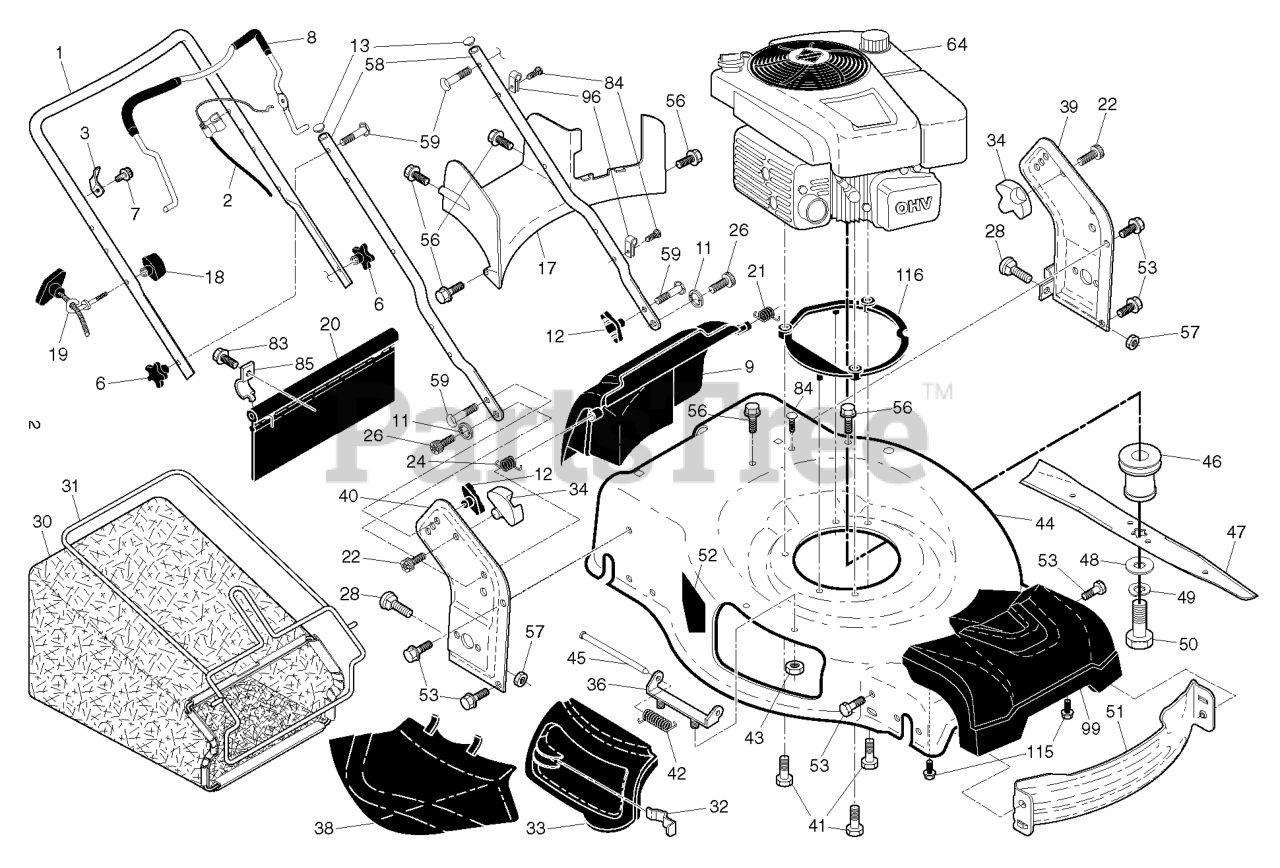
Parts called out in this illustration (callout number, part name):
1	HANDLE.UP.3POS.BS.AW2.GREY
2	CABLE.MZR.50.SNAP-IN
3	BRACKET.UPSTOP.RT
6	KNOB.HANDLE.PLASTIC.STAR.BLACK
8	BAIL.OVER.MOLD.ERGO.MZR.ORANGE
9	DOOR.REAR.ASM.22+.HUSQ.FG/RGD
11	E-RING.12MM.SHAFT
12	KNOB, DEFLECTOR
13	PLUG.PLASTIC.7/8".14-20.GAUGE
17	BAFFLE.REAR.22+RGD.AWD.PLASTIC
18	T-KNOB.NEW ROPE GUIDE
19	GUIDE.ROPE.BLK.ZINC.CHROM
20	SKIRT.REAR.22PLUS.RGD.LW(2 2MC
21	SPRING.LH.BLACK
22	SCREW.PAN.HEAD.#10
24	SPRING.RH.GRAY
26	SCREW,DOOR/HANDLE.PIVOT
28	BOLT.CARRIAGE.LN.5/16-18X.5/8
30	GBAG.B561029EM.GRY/SILV
31	FRAME.GBAG.22+.BLK
32	LATCH.DOOR.ZINC
33	DOOR.MULCH.22 PLUS.HUSQ.GREY
34	BRACKET.GRASSBAG.ATTACHING.BLK
36	BRACKET.ASM.HINGE.21.FWGD.
38	DEFLECTOR.CLIPPING.22.BLACK
39	BRACKET.ASM.HANDLE.LT.22+.GREY
40	BRACKET.ASM.HANDLE.RT.22+.GREY
42	SPRING.TORSION
43	NUT.FLANGE.1-4-20-SERR
44	KIT.HSG.22+AWD.MC.WO.668.TRI
45	ROD.HINGE.21
46	ADAPTER.BLADE.25M.B&S.AWD
47	BLADE.22PLUS
48	WASHER,HARDEN
49	LOCKWASHER
50	BOLT.BLADE
51	BAFFLE.FRONT.22.PLUS
52	DANGER DECAL
53	BOLT.5/16HEX.WHS.HD
56	SCREW.HX.13X.750
57	NUT.FLANGE.5/16
58	HANDLE.LOWER.22+.BT.GRAY
59	BOLT, HANDLE 5/16-18X1.75
83	TAPPING SCREW
84	FASTENER.PUSH.O.250X0.783
85	BRACKET.SKIRT.22+.BZP
96	CLIP.CABLE.BLK
99	COVER.ASSEMBLY.FRONT.22+AWD
115	SCREW.SHOULDER.5/16X1.375
116	SPACER.AWD.B&S
